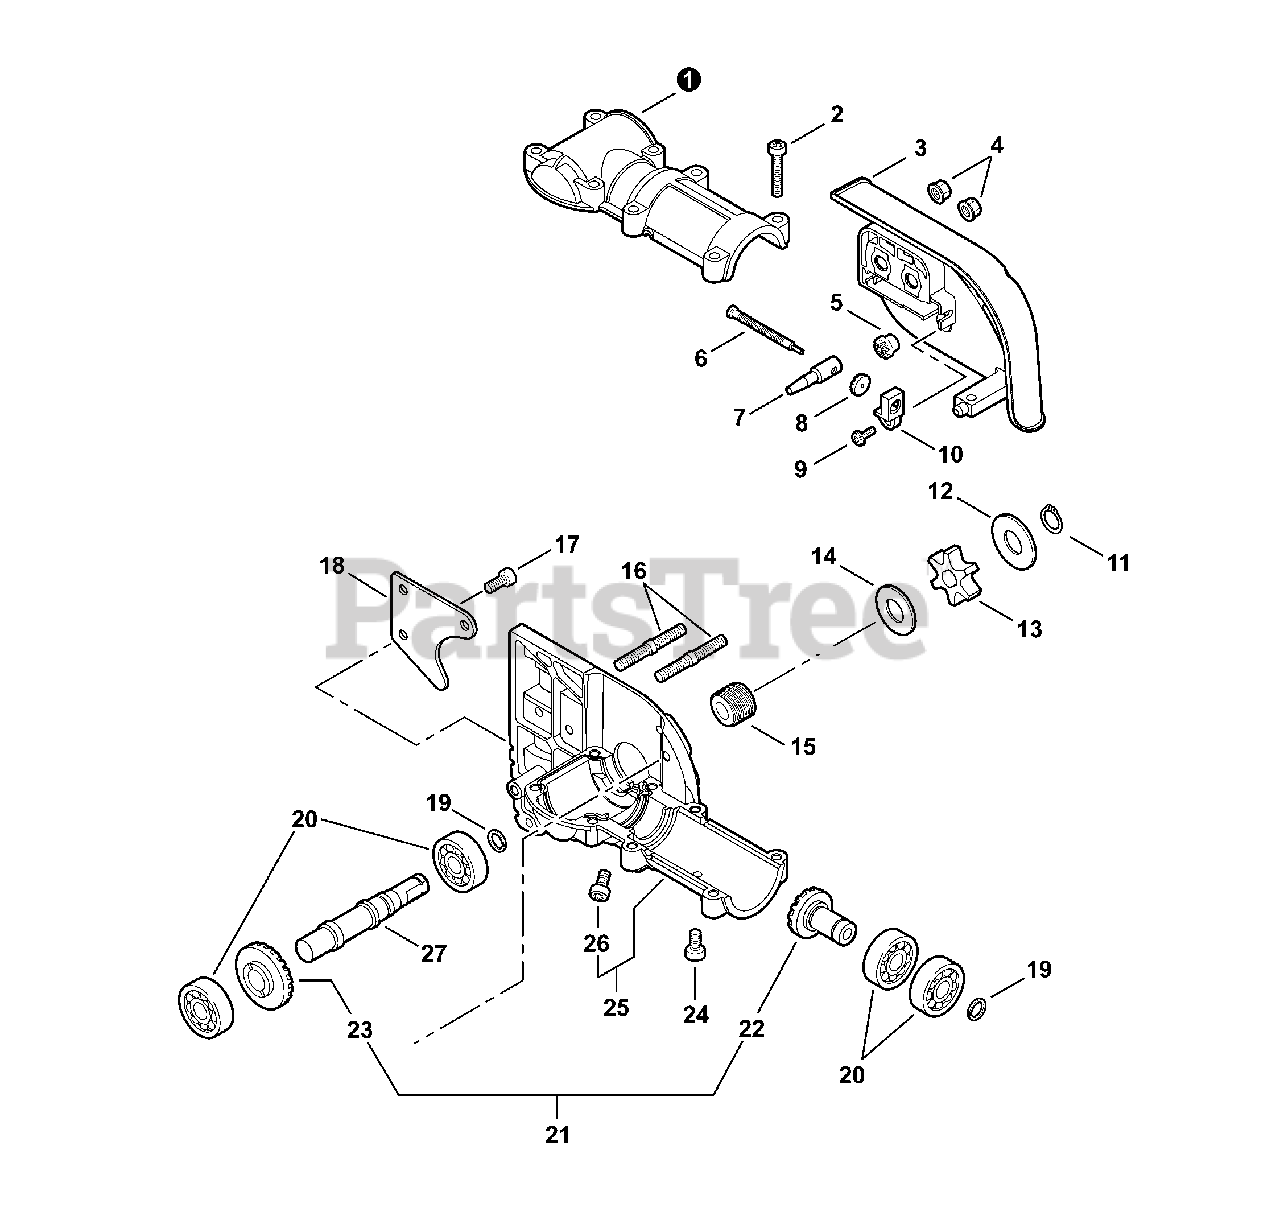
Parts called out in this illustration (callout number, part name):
1	COVER, GEAR CASE
2	BOLT, TORX 5×25
3	GUARD, SPROCKET
4	NUT, FLANGE M6
5	GEAR - 14 TOOTH
7	TENSIONER, CHAIN
8	GEAR - 14 TOOTH
9	SCREW 4
10	COLLAR 8
11	RING, SNAP
12	WASHER 10
13	SPROCKET, DRIVE
14	WASHER 10.2×24.5×1.2
15	GEAR, WORM
16	BOLT, STUD 6
17	SCREW 5×10
19	RING, SNAP Ø12
20	BEARING, BALL
21	GEAR SET
22	GEAR, BEVEL
23	GEAR, BEVEL - 23 TOOTH
24	BOLT, TORX 5×10
25	CASE, GEAR
26	BOLT, TORX 5×10
27	SHAFT, GEAR
